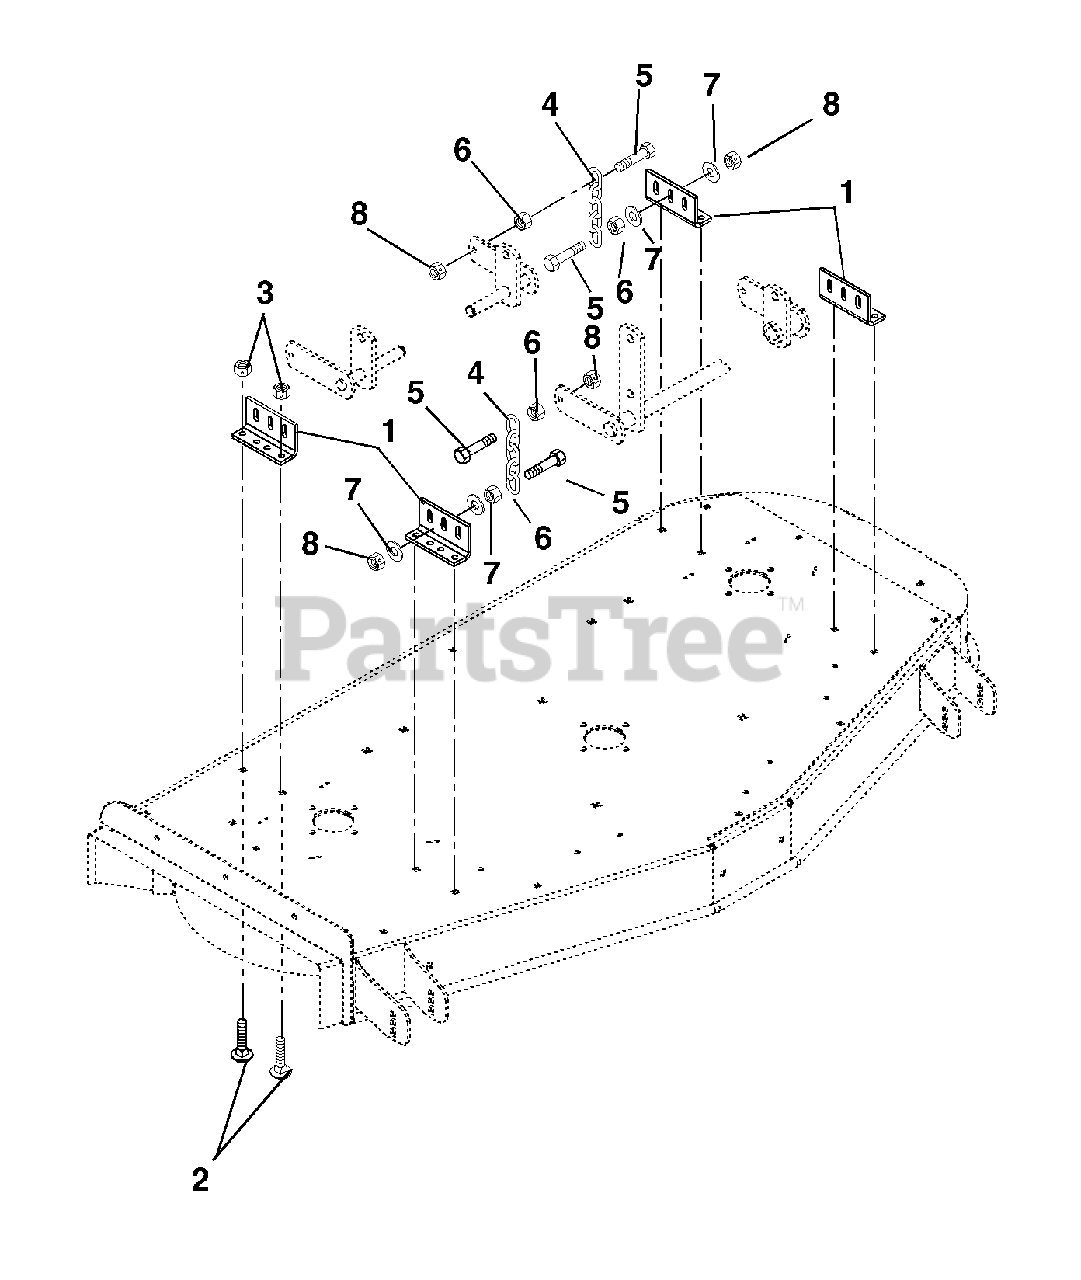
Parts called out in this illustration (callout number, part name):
1	Bracket, Mower Mounting
2	Bolt-Round Head Square Neck .38-16X1.25 Grade 5
3	Nut-Locking-Nylon .38-16
4	Chain, Link
5	Bolt-Hex .38-16 x 1.50 Grade 5
6	Nut-Hex .38-16
7	Washer-Flat-Steel .406 x .812 x .065
8	Nut-Locking-Center .38-16
